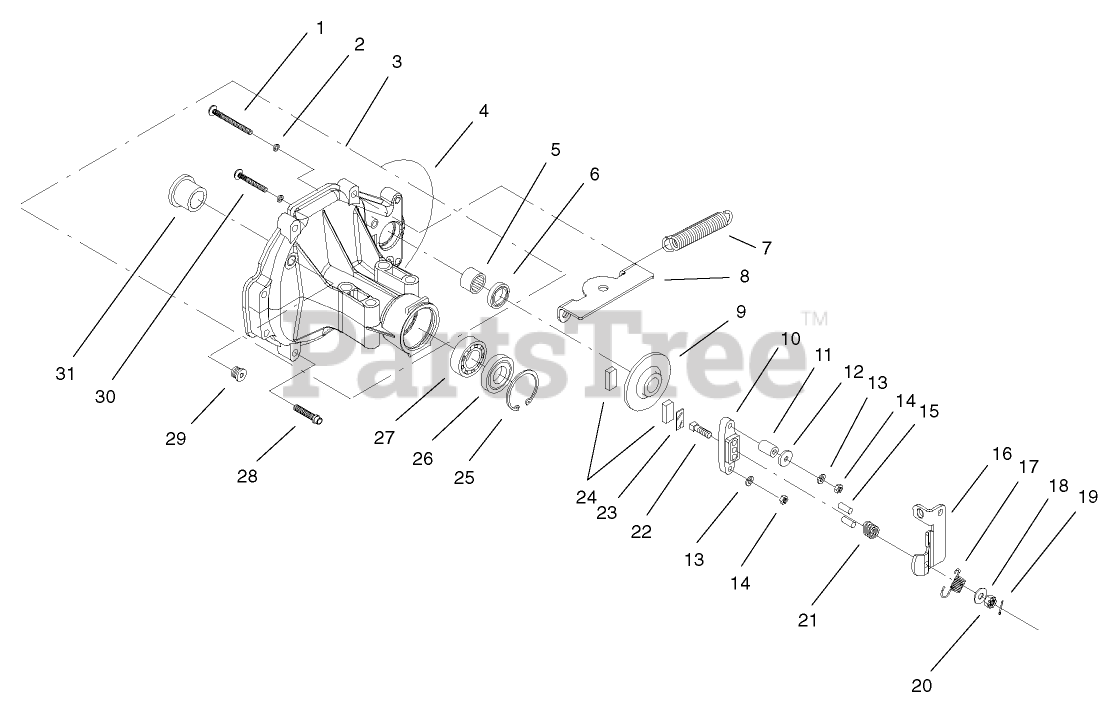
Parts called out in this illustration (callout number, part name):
2	O-RING
3	RH HOUSING ASM
4	SEALANT
5	BEARING-NEEDLE
6	SEAL-LIP
7	SPRING-RETURN
8	BRACKET-CRANK, BELL
9	DISK-BRAKE
10	YOKE-BRAKE
11	SPACER
12	WASHER
13	WASHER-LOCK
15	PIN-BRAKE
16	ARM-BRAKE
17	SPRING-ARM, BRAKE (BIAS)
20	NUT-CASTLE
21	SPRING-BRAKE, ANTI DRAG
22	BOLT-SQH
23	PUCK-PLATE
24	PUCK-BRAKE
25	RING-RETAINING
27	BEARING-BALL
28	SCREW-TTH
29	PLUG-THREAD, STRAIGHT
31	BEARING-FLANGE
